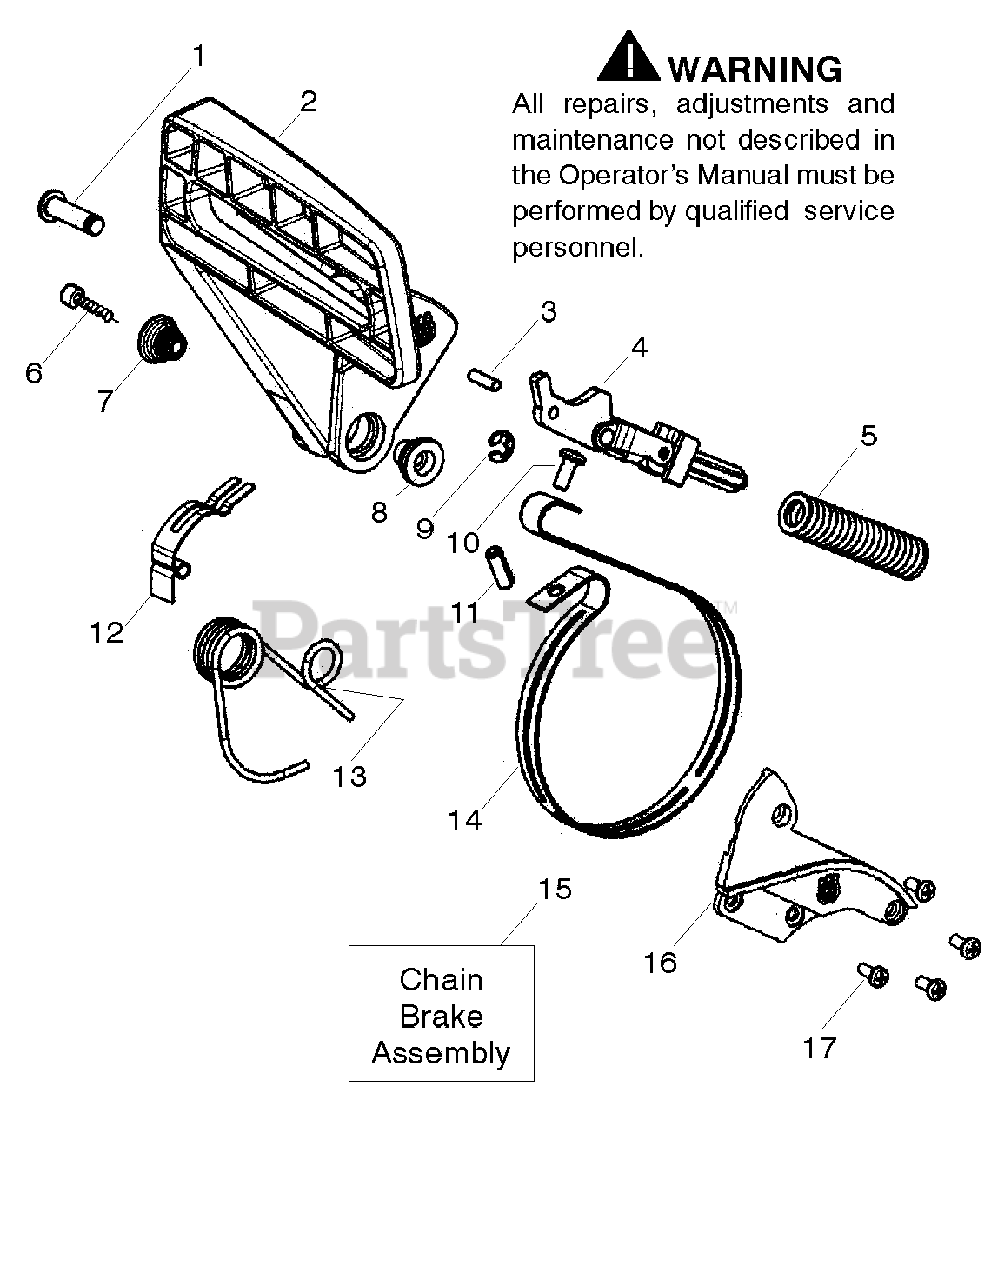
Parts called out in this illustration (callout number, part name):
2	Kit- Lever & Link Assy.
4	Assy-Front Link
5	Spring-Chain Brake
7	Journal-Right
8	Journal-Left
10	Screw
11	Pin-Spring
12	Spring-Position
13	Spring-Handguard
14	Band-Brake
15	Assy-Chain Brake
16	Cover-Chain Brake Spring
17	Screw
